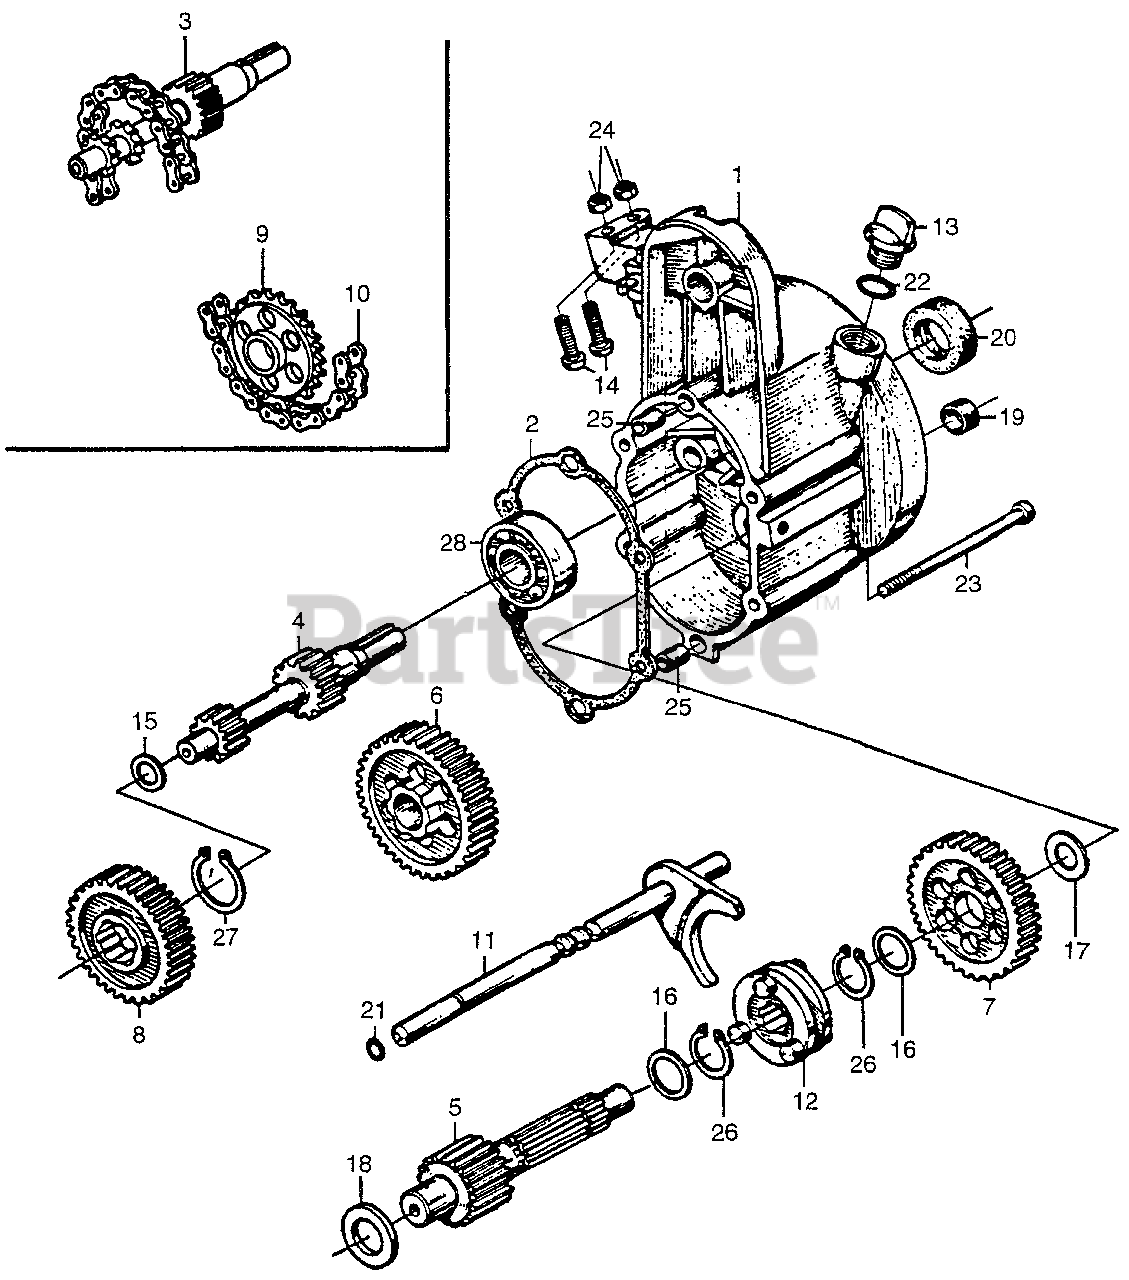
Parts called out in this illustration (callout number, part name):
1	COVER, R. SIDE
2	GASKET, R. SIDE (NOT AVAILABLE)
4	SHAFT, INPUT
5	COUNTERSHAFT
6	GEAR, LOW COUNTER
7	GEAR, FINAL
8	GEAR, COUNTER (2ND.)
11	SHAFT, SHIFT FORK
12	INSULATOR, PLATE (NOT AVAILABLE)
13	CAP, OIL (NOT AVAILABLE)
14	BOLT, ADJUSTING
15	WASHER (12MM) (NOT AVAILABLE)
16	WASHER, THRUST (17MM)
17	WASHER (12MM)
18	WASHER, THRUST (17MM) (NOT AVAILABLE)
19	OIL SEAL (20X36X7) (NOK)
20	OIL SEAL (15M/M) (NOT AVAILABLE)
21	O-RING (7MM)
22	O-RING (16MM)
22	O-RING (15.8X2.4) (SHOWA)
23	SCREW, PAN (6X80)
24	NUT, HEX. (6MM)
25	PIN A, DOWEL (8X10)
26	CIRCLIP (OUTER) (17MM)
27	CIRCLIP (OUTER) (25MM)
28	BEARING, RADIAL BALL (6004)
